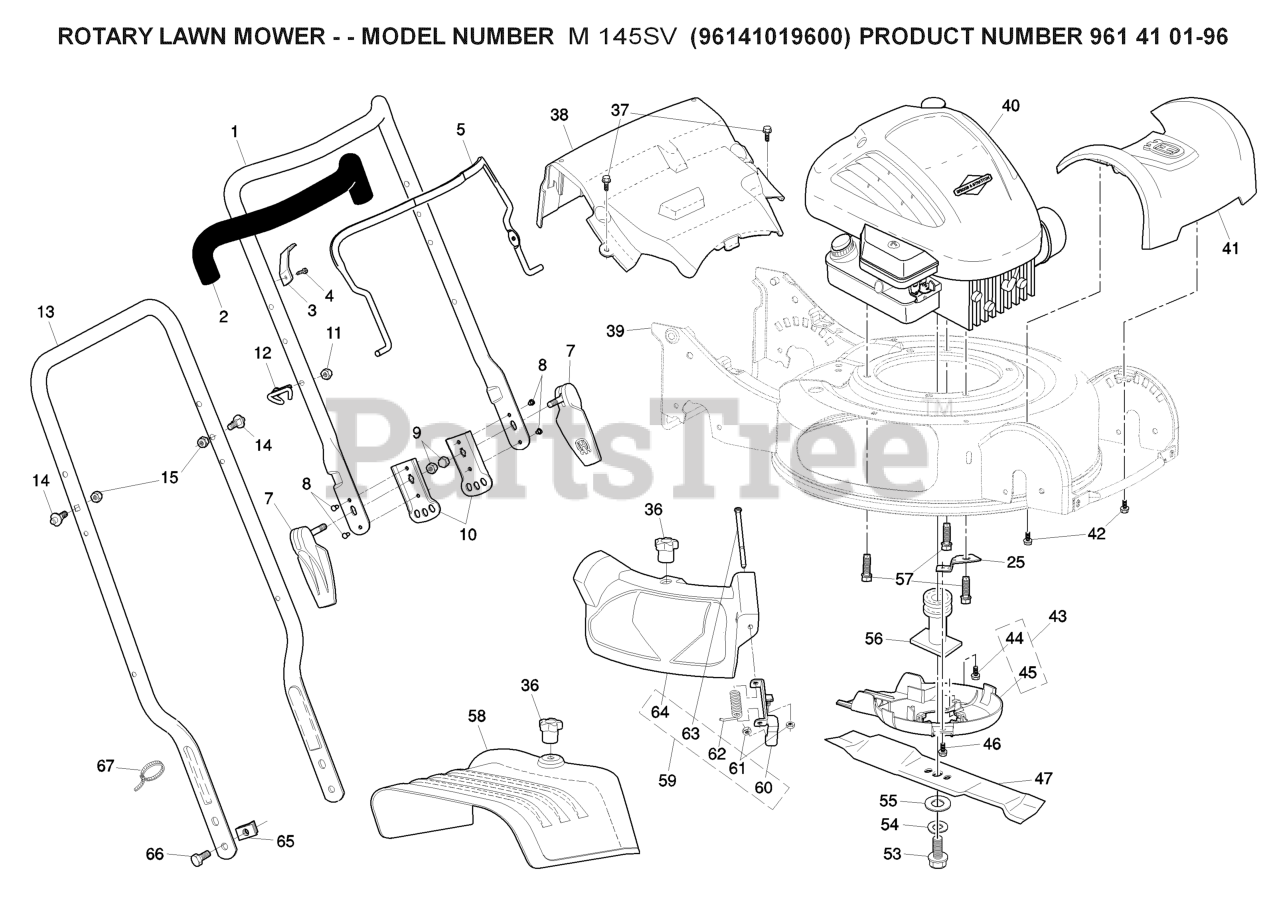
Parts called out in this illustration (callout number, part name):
1	HANDLE.ASM.UP.W/ADJ.BKT
2	GRIP.HANDLE.FOAM.WIDE.(1 SIDE)
3	BRACKET
5	BAIL CONTROL
6	CONTROL.ZONE.ASM
7	ASM.QUICK.RELEASE
9	Locknut, Hex 1/4-20
10	BRACKET.ADJ.3POS.GREY
11	NUT
12	RB GUIDE.ROPE.STD.BLK.ZIN WSL
14	STUD.QUICK.ADJUST
15	NUT.LOCK.5/16-18
25	BRACKET
36	KNOB.MULCH.DOOR
37	SCREW, HEX WASHER HEAD
42	SCREW.HWH.13-16-5.8.BZP
44	HINGE SCREW
46	SCREW.HEX.WSH
53	BOLT.HD.HEAD.3/8-24X2.50 (2 2)
54	LOCKWASHER
55	WASHER,HARDEN
57	BOLT 3/8-16X1-1/8
61	NUT.HEX.FLANGE.1/4
62	SPRING.MULCH.DOOR
63	ROD.HINGE.1/4"3.82"
64	DOOR.MULCH.GREY
67	TIE GUIDE
